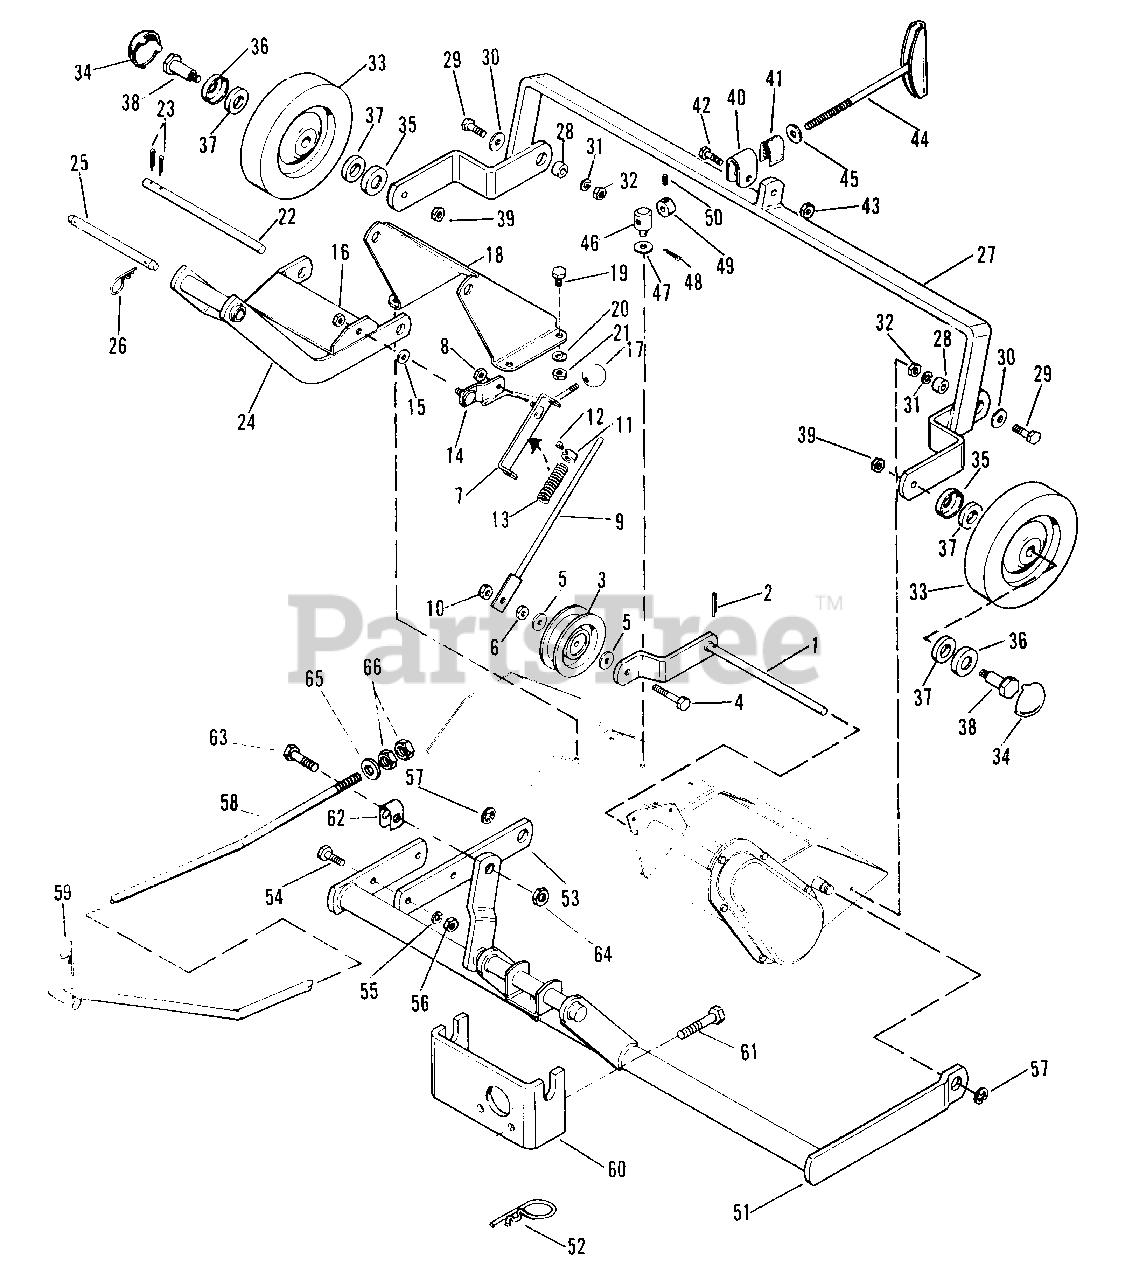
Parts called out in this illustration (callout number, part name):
1	Idler Arm Assembly
2	Cotter Pin, 1/8 x 1" lg.
3	Idler Pulley
4	Hex Capscrew, 3/8"-16 x 1-3/4" lg.
5	Plain Washer, 5/16"
6	Hex Nut, Full, 3/8"-16
7	Rod Guide Assembly
8	Hex Nut Full Lock, Jam, 5/16"-18
9	Clutch Rod Assembly
10	Hex Nut, Full, 3/8"-16
12	Set Screw, Sq. Hd., Clip Pt. 1/4"-20 x 3/8"
14	Clutch Lever Assembly
15	Special Washer
16	Hex Nut, Full, 5/16"-18
18	Arm Support
19	Hex Capscrew, 5/16"-18 x 5/8" lg.
20	Lock Washer, 5/16"
21	Hex Nut, Full, 5/16"-18
22	Pivot Pin
23	Cotter Pin, 1/8" x 1" lg.
24	Link Assembly
26	Spring Clip
27	Frame Assembly
29	Hex Capscrew, 3/8"-16 x 1" lg.
30	Plain Washer, 5/16"
31	Lock Washer 3/8"
32	Hex Nut, Full, 3/8"-16
35	Seal Housing
36	Seal Housing
37	Wheel Seal
38	Wheel Bolt
39	Hex Nut, Lock, Jam 3/8"-16
42	Hex Capscrew, 5/16"-18 x 1-1/4" lg.
43	Hex Nut Full, Lock, 5/16"-18
44	Adjusting Screw Assembly
45	Plain Washer, 3/8"
47	Plain Washer, 5/16"
48	Cotter Pin, 3/32" x 3/4" lg.
49	Set Collar
50	Soc. Hd. Set Screw, Hollow Pt., 1/4"-20 x 5/16" lg.
51	Hitch Assembly
52	Spring Clip
53	R.H. Pivot Bar
54	Hex Capscrew, 5/16"-18 x 1" lg.
55	LockWasher, 5/16"
56	Hex Nut, Full, 5/16"-18
57	"E" Ring
59	Spring Clip
60	Attachment Hitch
61	Hex Capscrew, 3/8"-16 x 1-1/4" lg.
63	Hex Capscrew, 5/16"-18 x 1-1/2" lg.
64	Hex Nut, Full, Lock, 5/16"-18
65	Plain Washer, 7/16"
66	Hex Nut, Jam, 1/2"-20
